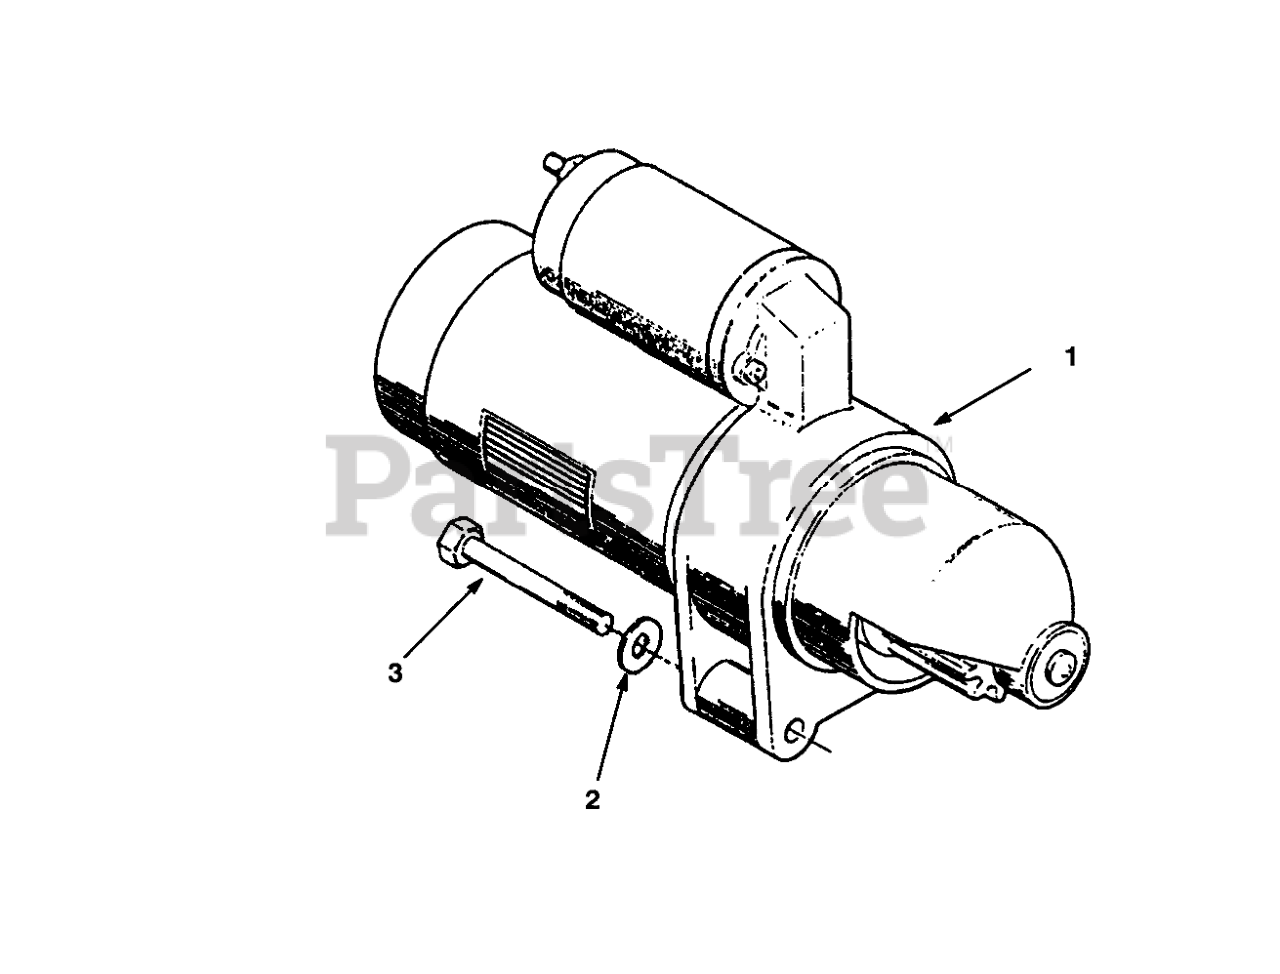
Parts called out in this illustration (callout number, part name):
1	STARTER
2	Washer
3	Cap Hex Hd
